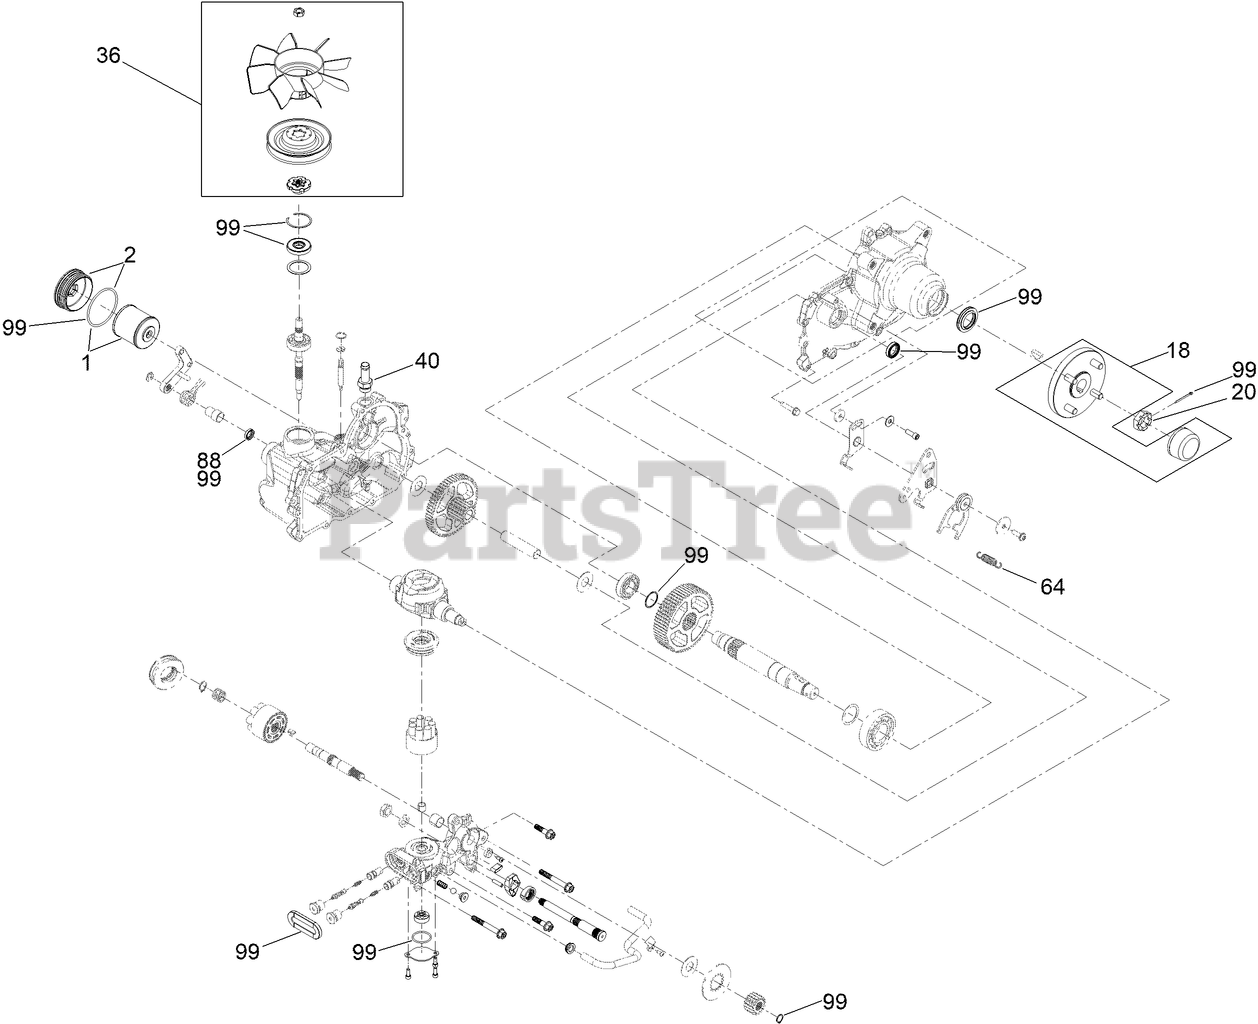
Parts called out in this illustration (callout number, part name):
1	KIT, FILTER
2	KIT, FILLER CAP
18	HUB-4 BOLT
20	NUT, SLOTTED
36	KIT, FAN AND PULLEY
40	FITTING-5/8 BEADED, 7/8 SAE
64	SPRING-EXTENSION
88	SEAL, BRAKE
99	KIT, SEAL
